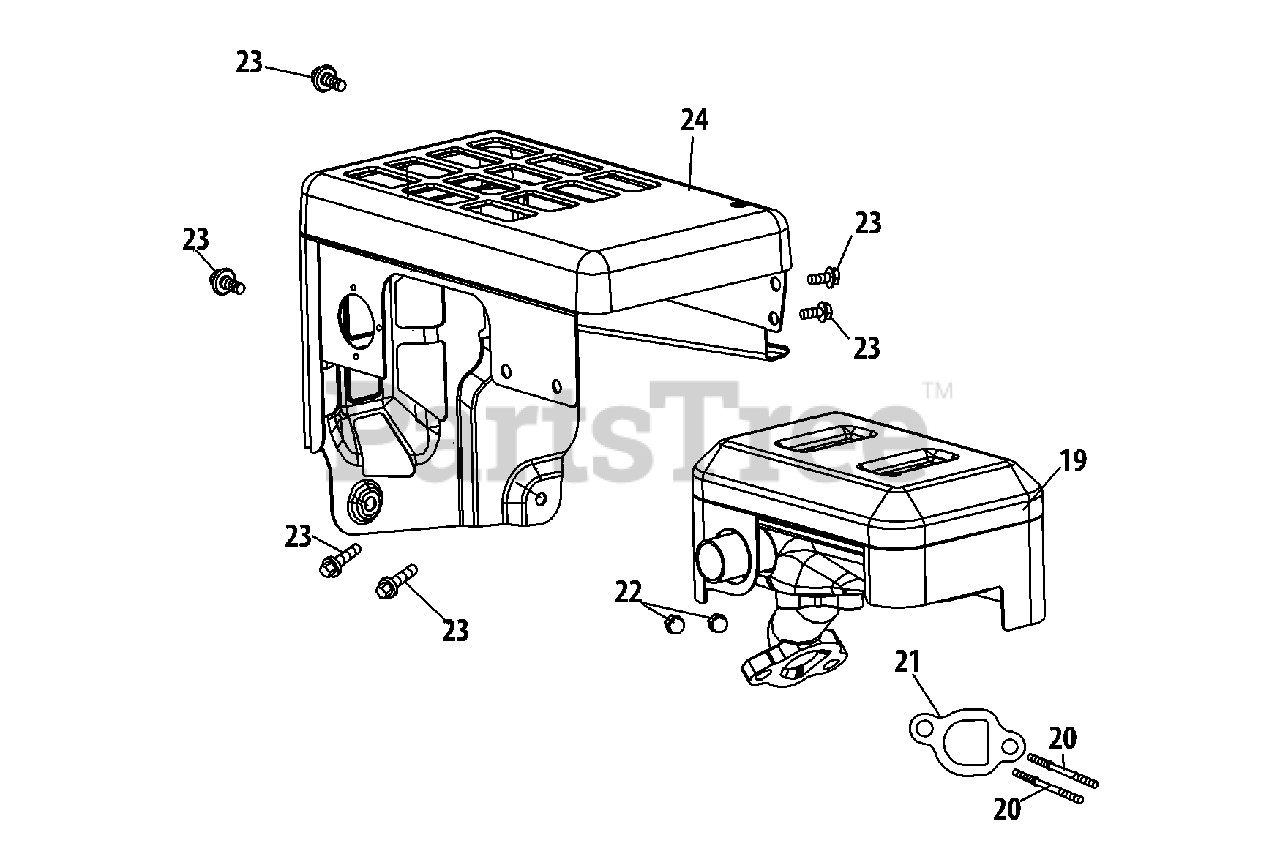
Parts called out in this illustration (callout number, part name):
19	Muffler Assembly
20	Stud M8×36
20	Muffler Stud Kit
21	Exhaust Pipe Gasket
23	Bolt M6×12
24	Muffler Shield
